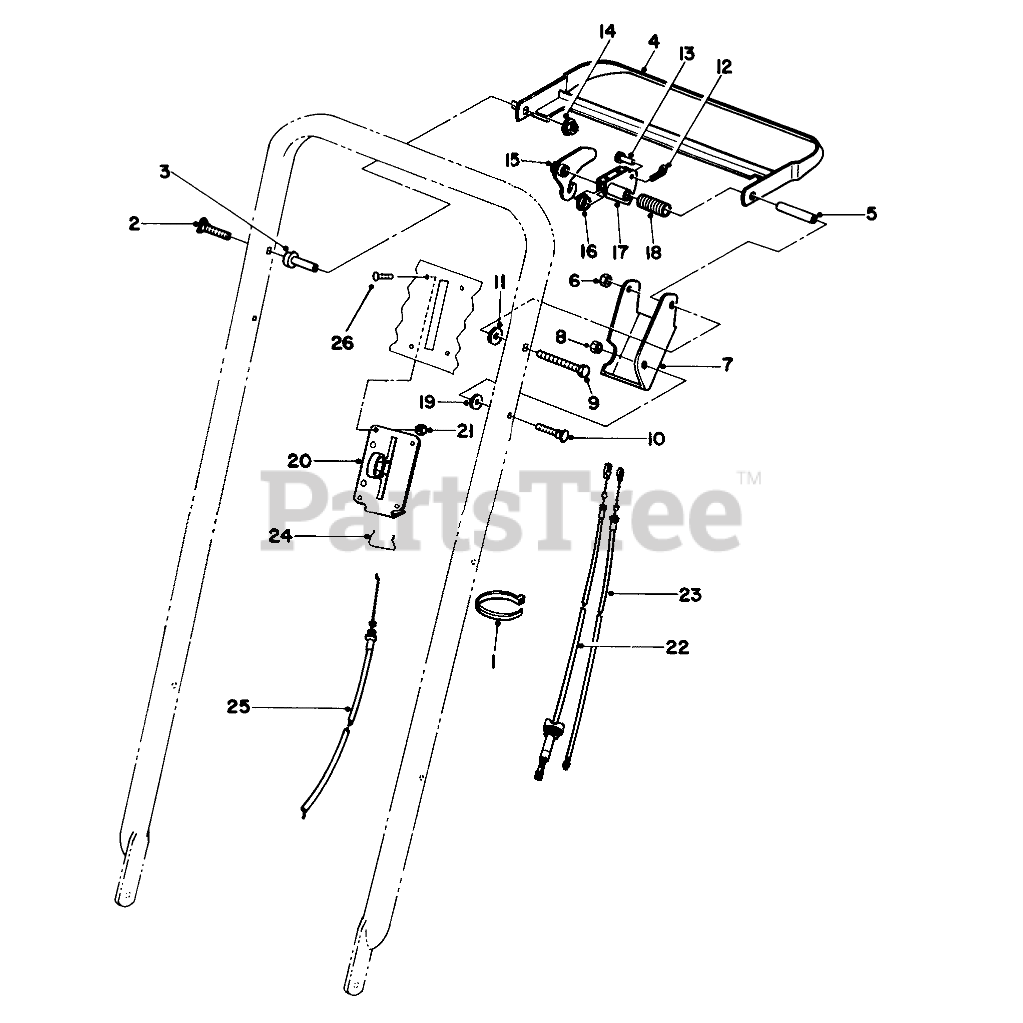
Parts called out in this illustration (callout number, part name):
1	TIE-CABLE
2	SCREW
3	SPACER-SUPPORT
4	Bar-Control
5	SPACER-BRACKET, CONTROL
6	NUT-LOCK, NI
7	Bracket-Control
8	NUT-LOCK, NI
9	SCREW-HH
10	SCREW-HANDLE
11	SPACER
12	PIN-COTTER
13	PIN-CABLE
14	NUT-LOCK, NI
15	LEVER-TRACTION
16	BUSHING-FLANGE
17	LEVER-BBC
18	SPRING-CONTROL
19	SPACER
20	CONTROL-THROTTLE
21	NUT-LOCK, NI
22	CABLE-TRACTION
23	CABLE-CLUTCH
24	RETAINER-CABLE, THROTTLE
25	THROTTLE CABLE
26	SCREW-PPH
